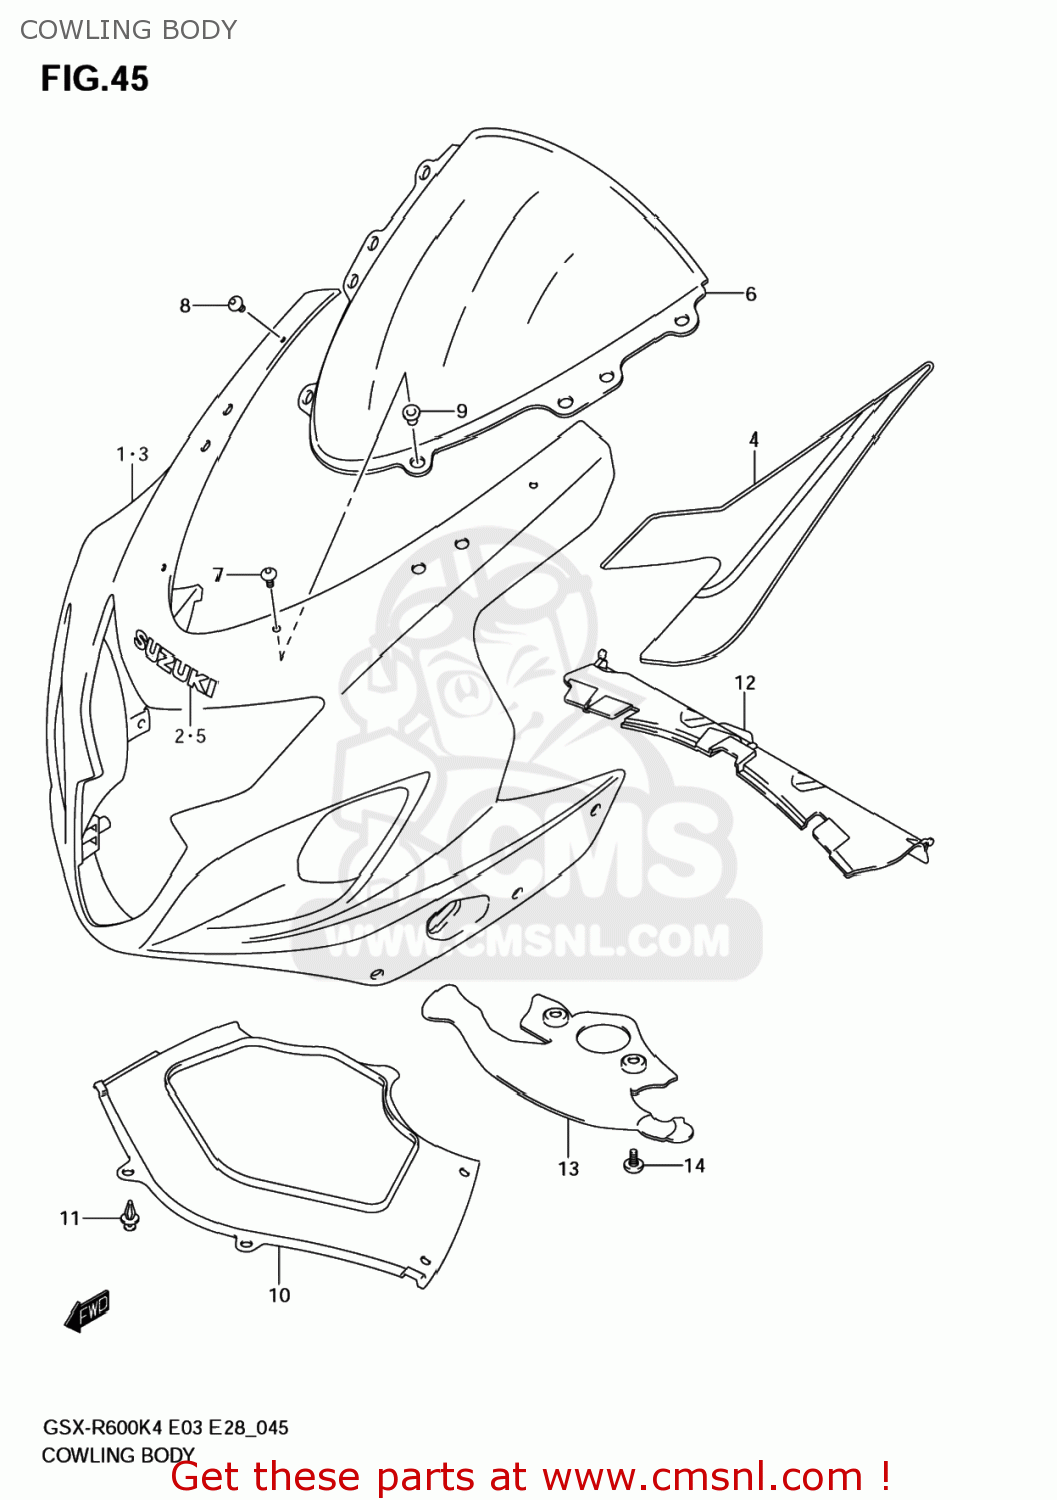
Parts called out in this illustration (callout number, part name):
1	COWLING ASSY,BODY
2	EMBLEM,SUZUKI
3	COWLING ASSY,BODY
4	TAPE SET,COWL BODY
5	EMBLEM,SUZUKI
6	WINDSCREEN
7	SCREW(5X18)
8	SCREW(5X15)
9	NUT
10	COVER,BODY COW
11	CLIP(BLACK)
12	COVER,COWLING FR LWR
13	COVER,LWR BRACKET
14	BOLT
